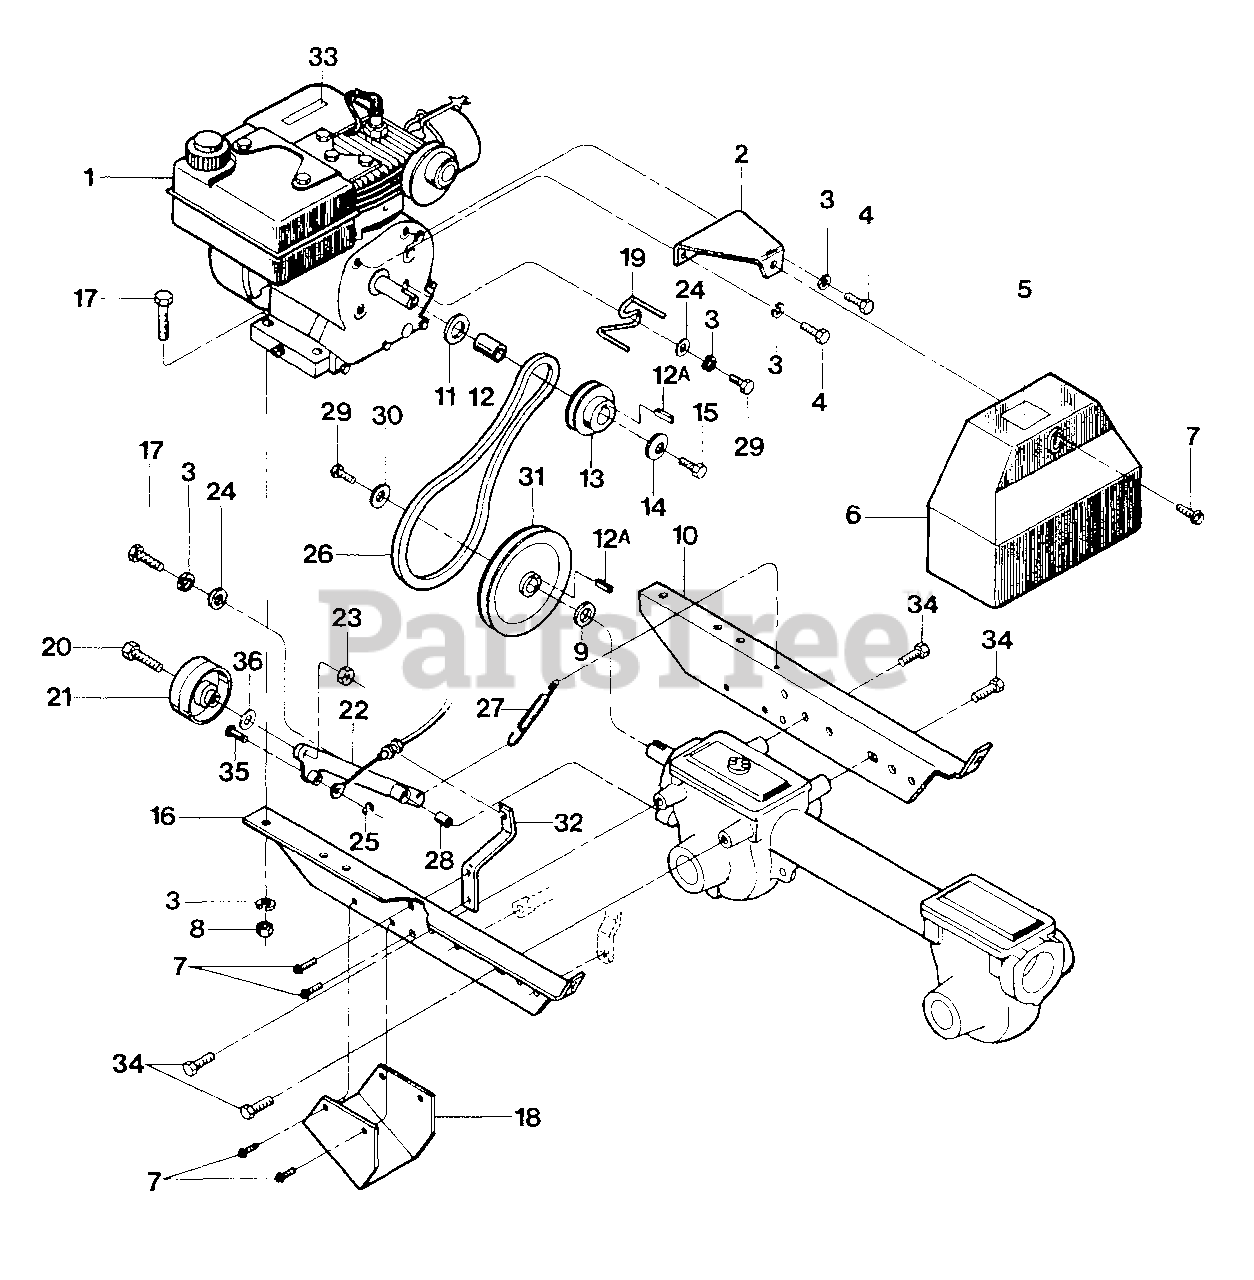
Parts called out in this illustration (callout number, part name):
1	Engine, Recoil Start
2	Bracket, Belt Cover
3	Lockwasher, 5/16
4	Hex Hd. Screw, 5/16-24 x 1/2
5	Decal, Hot Surfaces Warning
6	Belt Cover
7	Flange Screw, Self-Tapping, 1/4-20 x 1/2
8	Hex Nut, 5/16-18
9	Support Washer
10	Engine Bracket, Right
11	Shim
12	Spacer
12A	Key, 3/16 x 1
13	Pulley, Engine Drive
14	Belleville Washer
15	Hex Hd. Screw, 3/8-24 x 1, Grade 5
16	Engine Bracket, Left
17	Hex Hd. Screw, 5/16-18 x 1-1/2, Grade 5
18	Guard, Belt/Pulley
19	Belt Guide
20	Hex Hd. Screw, 3/8-16 x 1-1/2
21	Idler Pulley
22	Idler Lever
23	Locknut, 3/8-16
24	Flat Washer
25	Klip Ring
26	V-Belt
27	Return Spring
28	Bushing, Idler Lever
29	Hex Hd. Screw, 5/16-24 x 3/4, Grade 5
30	Belleville Washer, Belleville
31	Transmission Pulley
32	Bracket, Cable Mount
33	Decal, Stabilization
34	Hex Hd. Screw, 5/16-18 x 5/8
35	Clevis Pin
36	Flat Washer, 3/8
